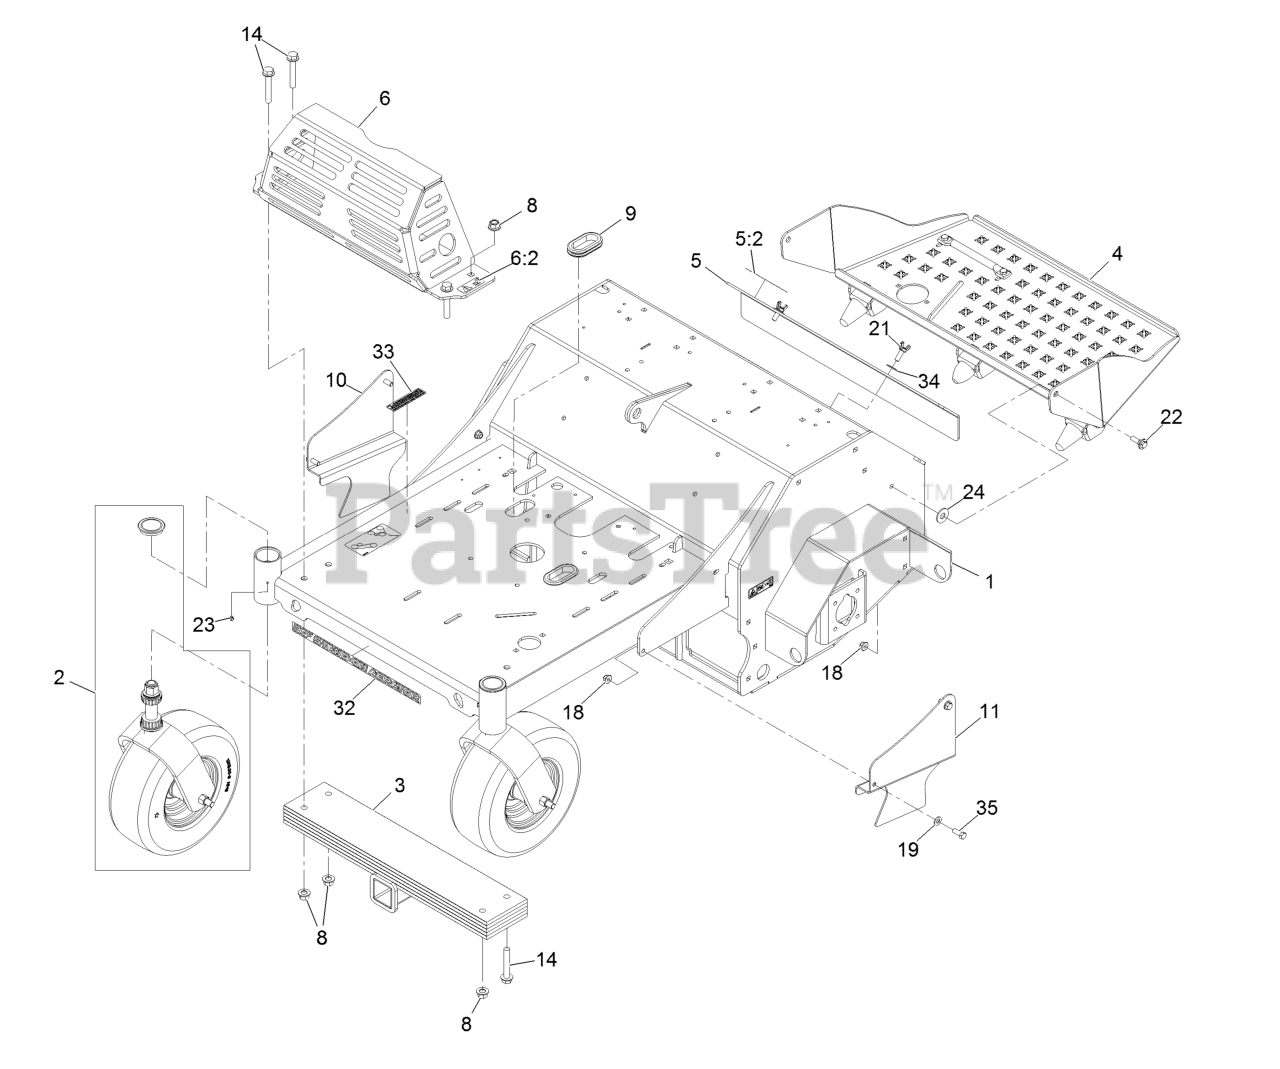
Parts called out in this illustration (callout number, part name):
1	Main Frame ASM
2	Front Caster ASM W/Fork
4	Platform ASM W/Decal & Rocker
5	Access Cover ASM
5:2	Decal-Tine Ground Operation (CE)
6	Muffler Guard ASM
6:2	Decal-Surface, Hot
8	Nut-Lock 1/2-13
9	Grommet
10	Guard-Chain, RH
11	Guard-Chain, LH
14	Screw-HF
18	Nut-Nyloc 3/8-16 Flg
19	Washer-3/8 SAE
21	Screw-Thumb
22	Screw-Shoulder 3/8-16 X 1.295
24	Washer
32	Decal-Aerator 30 Logo
33	Decal-Arrester, Spark
34	Washer-Spring Disc
35	Screw-HH 3/8-16 X 1
